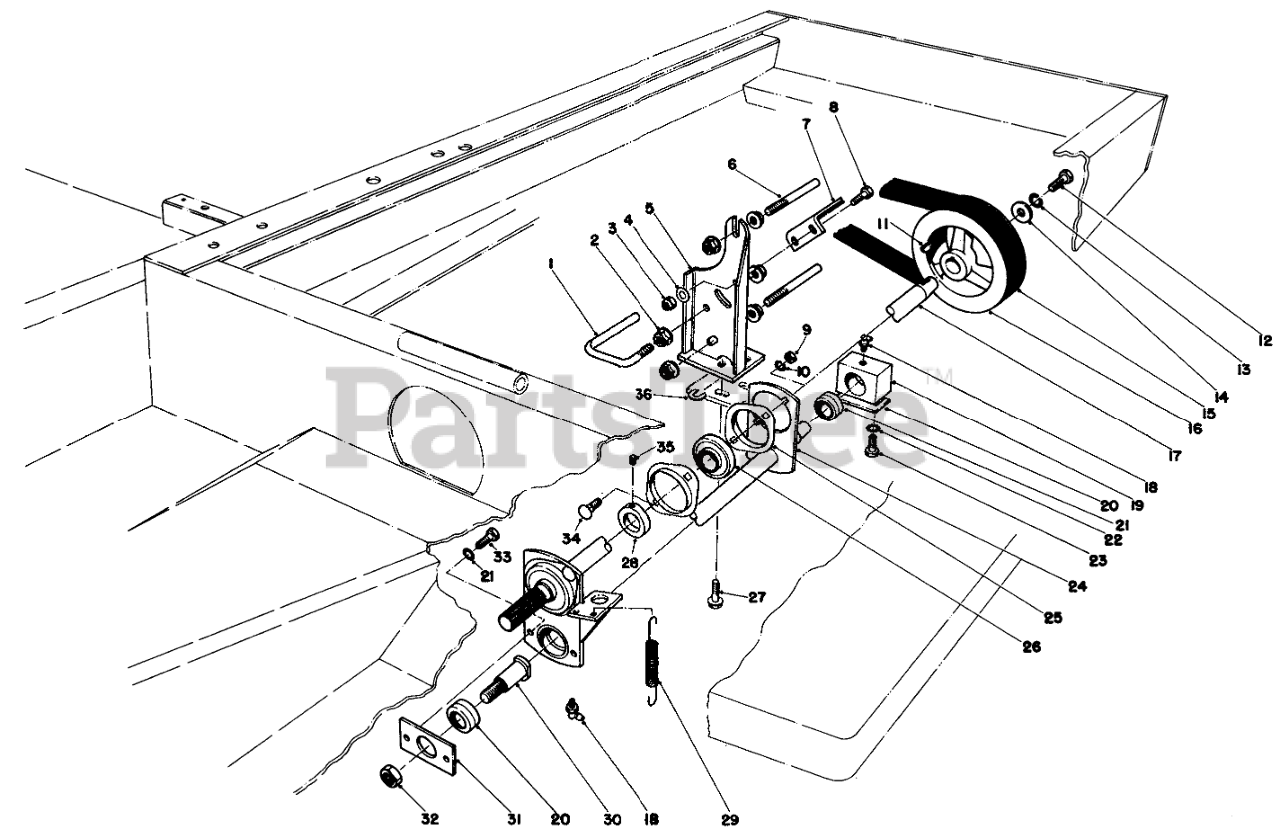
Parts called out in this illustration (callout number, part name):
1	LOWER BELT GUIDE
2	NUT-HHF, WHIZ
3	NUT-LOCK, NI
4	WASHER-PLAIN
5	Bracket-Brake
6	UPPER BELT GUIDE
7	PTO SUPT PAD ASM
8	SCREW-HH
9	NUT-HEX
10	WASHER-LOCK
11	KEY-WOODRUFF
12	SCREW-HH
13	WASHER-LOCK
14	WASHER-FLAT
15	V-BELT
16	Pulley-PTO
17	PTO SHAFT
18	FITTING-GREASE, 90 DEG
19	BEARING HUB PP
20	PTO SHIM BLOCK
21	BEARING
22	WASHER-LOCK
23	SCREW-HH
24	ARM WA - ENGAGE R
25	FLANGE
26	Bearing w/Collar (Incl. Ref. #28 & 35)
27	SCREW-HHF
28	COLLAR-LOCK, BEARING
29	TENSION PTO SPRING R
30	BEARING STUD
31	BRG RETAINER
32	NUT-LOCK, NI
33	SCREW-HH
34	SCREW-CARR
35	SCREW-SET, HSH
36	SPECIAL WASHER
